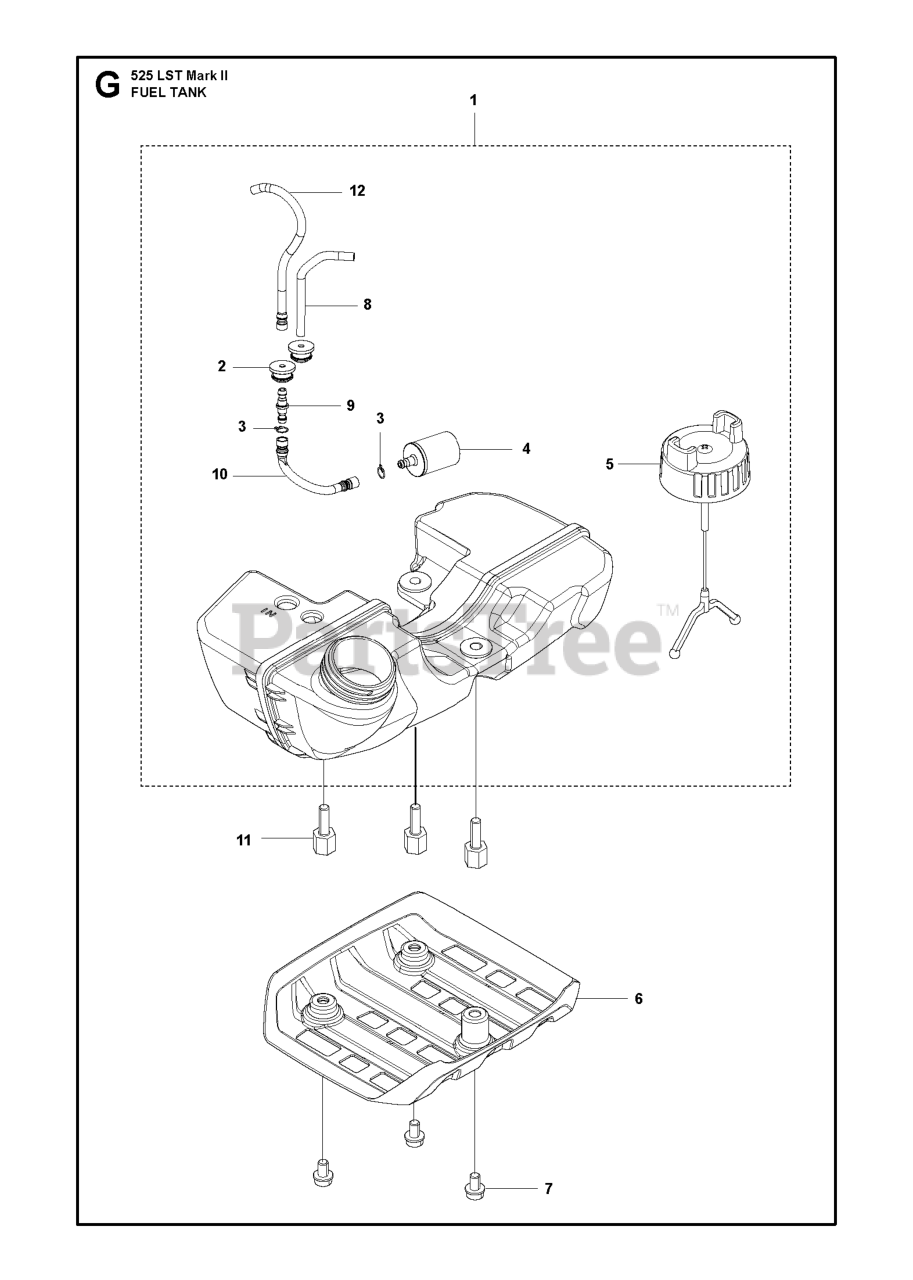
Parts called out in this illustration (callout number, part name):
1	FUEL TANK KIT
4	RP FUEL FILTER
6	SKID PLATE
10	FUEL HOSE L=80 ROHS2
11	STUD SCREW M5XM5
12	FUEL HOSE EPA NON CW CARB2020
